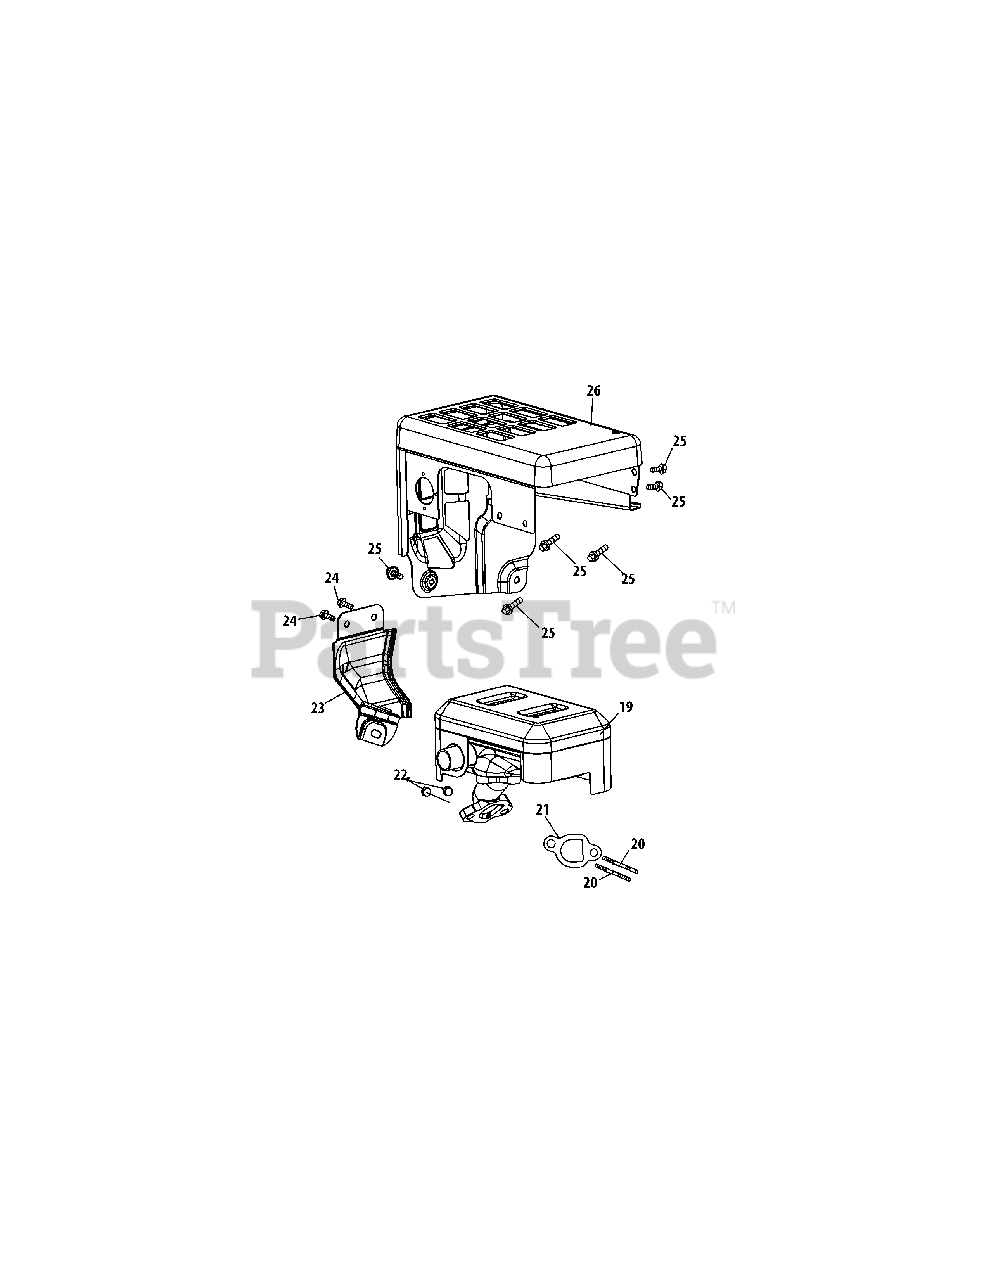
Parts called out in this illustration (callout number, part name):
19	Muffler Assembly
20	Stud M8×36
20	Muffler Stud Assembly
21	Exhaust Pipe Gasket
22	Nut, M8
23	Exhaust Pipe Shield
24	Bolt M6×10
25	Bolt M6×12
26	Muffler Shield
